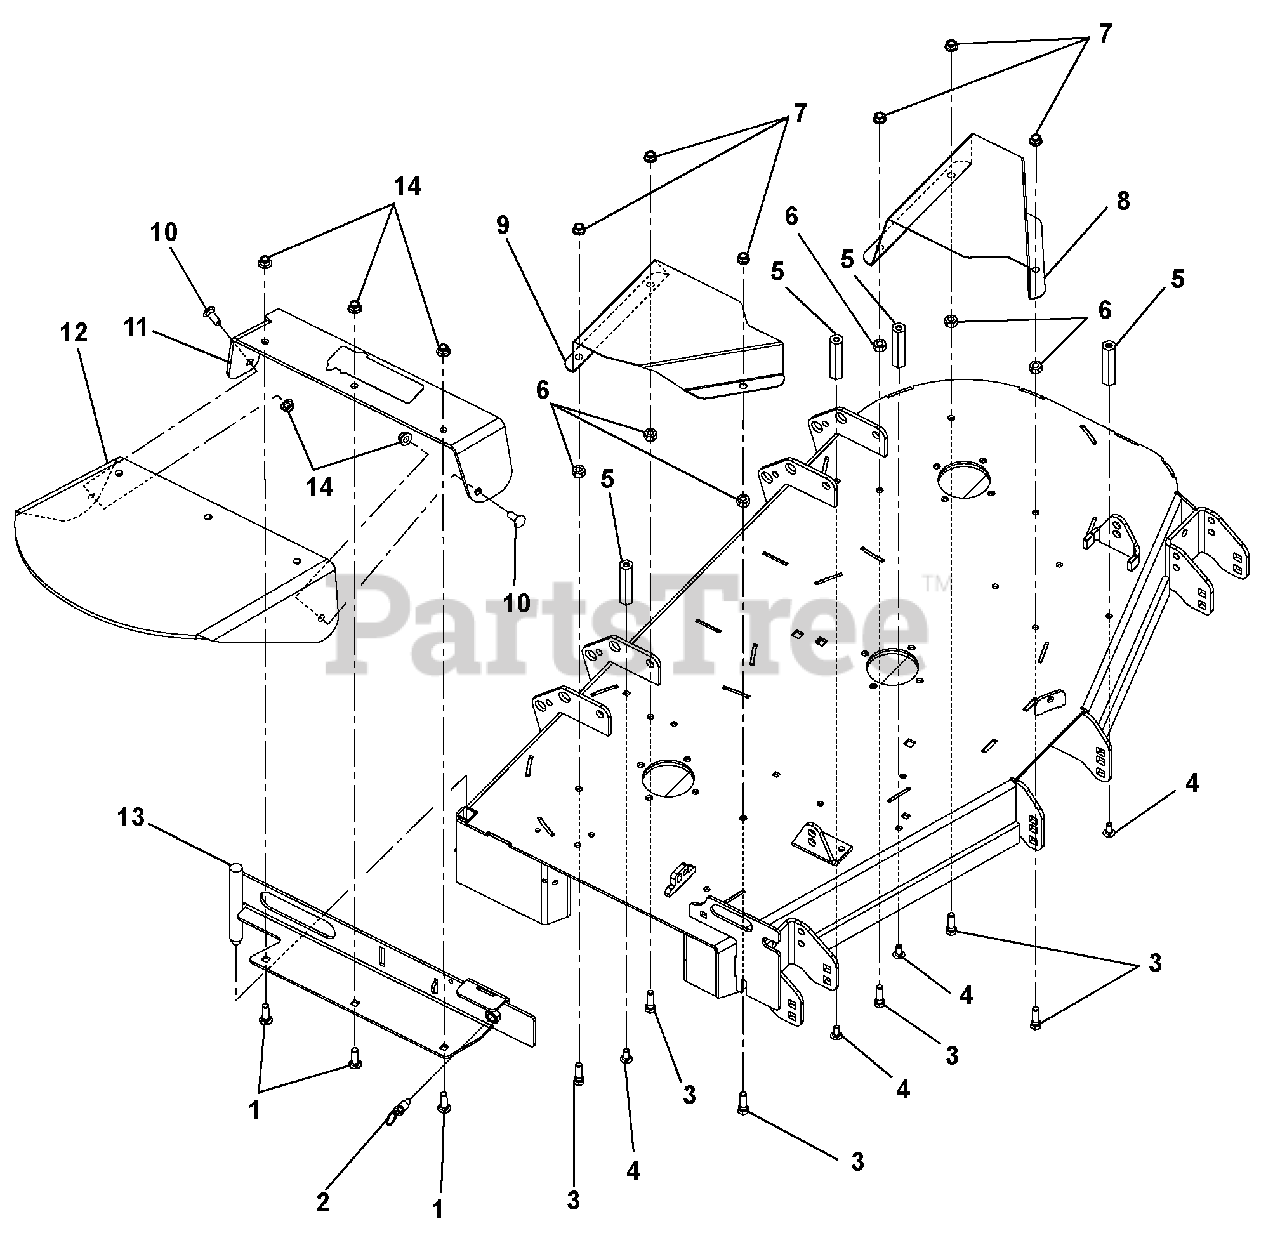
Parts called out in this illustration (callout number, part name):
1	BLT-RDHDSQNK .38-16X1.25 G5YZ
2	PULL PIN,.50-13THDX.310 PLNGR
3	BLT-HEX .38-16X1.25 GR5 YWZC
4	BLT,RDHDSQNK .31-18X.75 LOCTIT
5	NUT, COUPLING .31-18 X 3.00
6	NUT-HEAVY HEX .38-16 YWZC
7	NUT-SPNLK-FLG .375-16 YWZC
8	GUARD, 44-52 LH SPINDLE SHEAVE
9	GUARD, 48-52 SPINDLE SHEAVE
10	BLT-RDHDSQNK .38-16X1.00 G5YZ
11	RUBBER DISCH CHUTE SUPPORT-RED
12	CHUTE, RUBBER DISCHARGE
13	44"-48" DISCH CHUTE MTG WMT-RD
14	NUT-LK-NYL-FLG .38-16 YWZC
